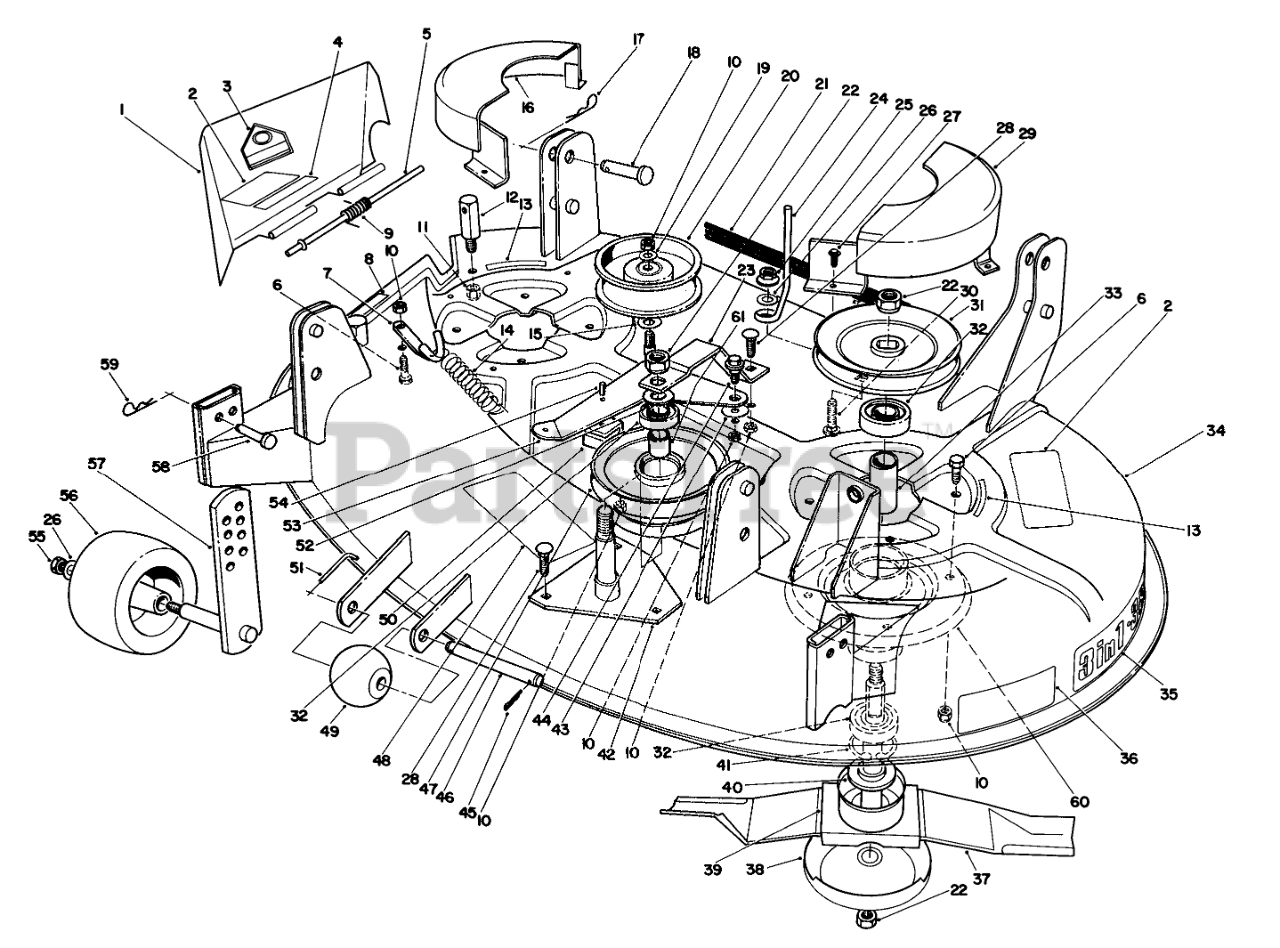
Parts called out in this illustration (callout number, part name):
1	Deflector Assembly (Incl. Ref. #2-4)
2	DECAL-DANGER, THROWN OBJECT
3	DECAL-DANGER
4	DECAL-NO STEP
5	ROD-HINGE DEFLECTOR
6	SCREW-HH
7	SPRING ROD
8	DECAL-DANGER, DEFLECTOR
9	SPRING
10	NUT-LOCK, NI
11	NUT-LOCK, NI
12	REAR PIVOT POST (PLTD)
13	DECAL-DANGER, SHIELD
14	DECK TENSION SPRNG O
15	WASHER-FLAT
16	RH BELT COVER WA B
17	PIN-HAIR
18	PIN-CLEVIS
19	WASHER-FLAT
20	PULLEY-IDLER
21	V-BELT
23	PULLEY SUPPORT B
24	BELT ROD
25	NUT-HF
26	WASHER-FLAT
27	SCREW-HWHTF
28	BOLT-CARR
29	Cover-Belt L.H.
30	SCREW-CARR
31	DECK PULLEY
32	BEARING-BALL
33	BEARING SPACER
34	Deck-38" (Incl. Ref. #8, 13, 35, 36 & 48)
35	DECK DECAL
36	DECAL - WHEEL ADJUSTMENT
37	Blade
38	Cup
39	SPINDLE SHAFT WA
40	IDLER SPACER
41	RING-RETAINING
42	JACK SHAFT WA B
43	WASHER-PIVOT
44	SCREW-SHOULDER
45	PIN-COTTER
46	SHAFT-ROLLER
47	PULLEY ASSEMBLY
48	BELT ROUTING DECAL
49	ROLLER
50	IDLER BRKT GUIDE
51	PIN-SPECIAL
52	WASHER-FLAT
53	IDLER BRACKET WA B
54	PIN-COIL
55	NUT-LOCK, NI
56	WHEEL-GAGE
57	GAGE-WHEEL
58	PIN-CLEVIS
59	PIN-HAIR
60	Spindle
61	BEARING SPACER
